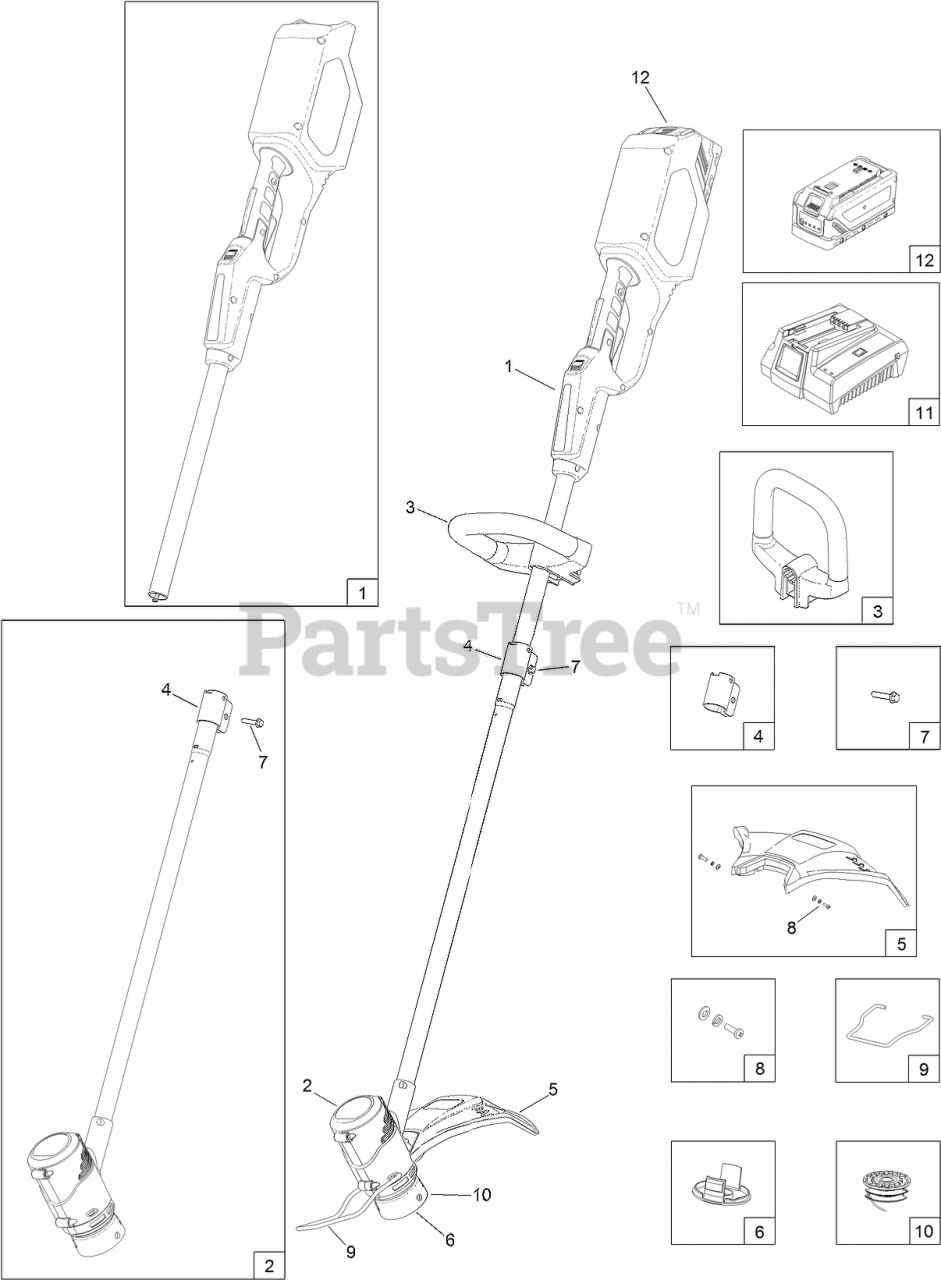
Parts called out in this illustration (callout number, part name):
1	HANDLE-UPPER
2	HOUSING-MOTOR, LOWER
3	HANDLE-ASSIST
4	CLAMP-CONNECTION, SHAFT
5	SHIELD-GRASS
6	CAP-RETAINER, SPOOL
8	SCREW WITH WASHERS ASM
9	WIRE-GUIDE, STRING TRIMMER
10	SPOOL-TRIMMER, SINGLE PACK
11	CHARGER-REPLACEMENT, 48V
12	BATTERY-REPLACEMENT, 48V
